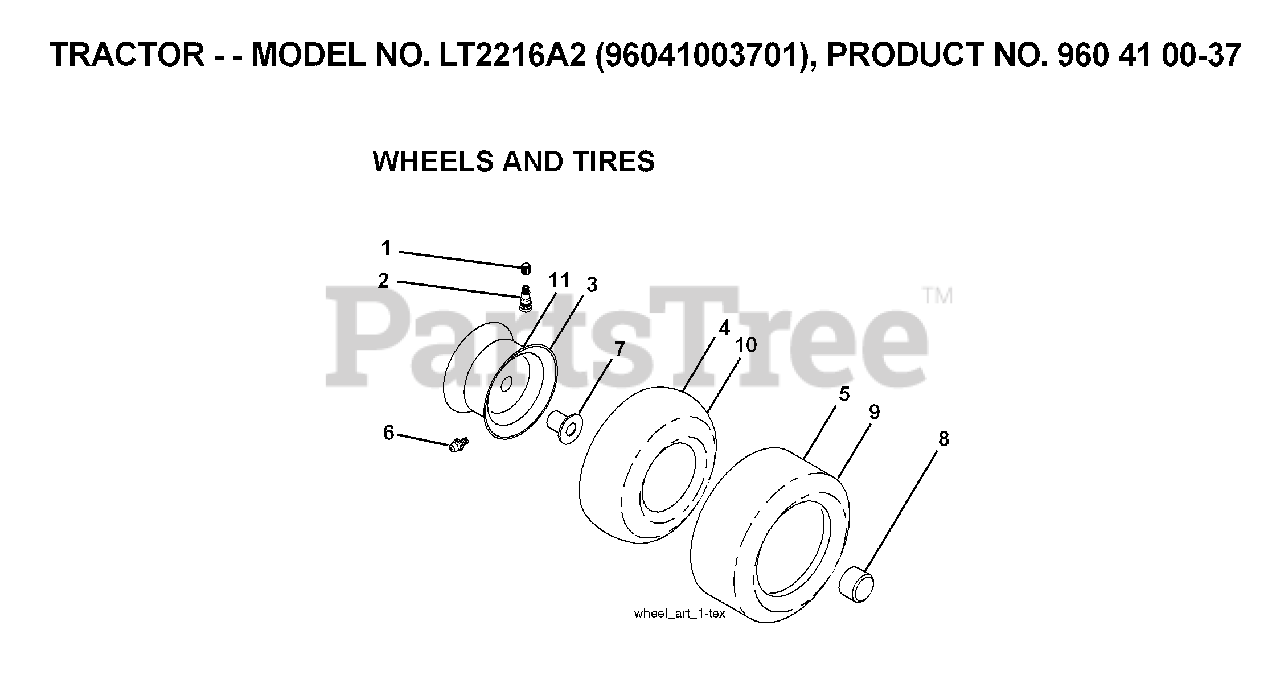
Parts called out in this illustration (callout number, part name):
1	VALVE CAP
2	VALVE STEM LT
3	RIM ASM 6" FRONT SILVER
4	TUBE.5.3/4.5/6
5	TIRE HEAVY DUTY
6	FITTING LT
7	BEARING T
8	CAP, AXLE BLK
9	TIRE.TS.20X10-8
10	TUBE
11	RIM ASM 8" REAR SILVER
